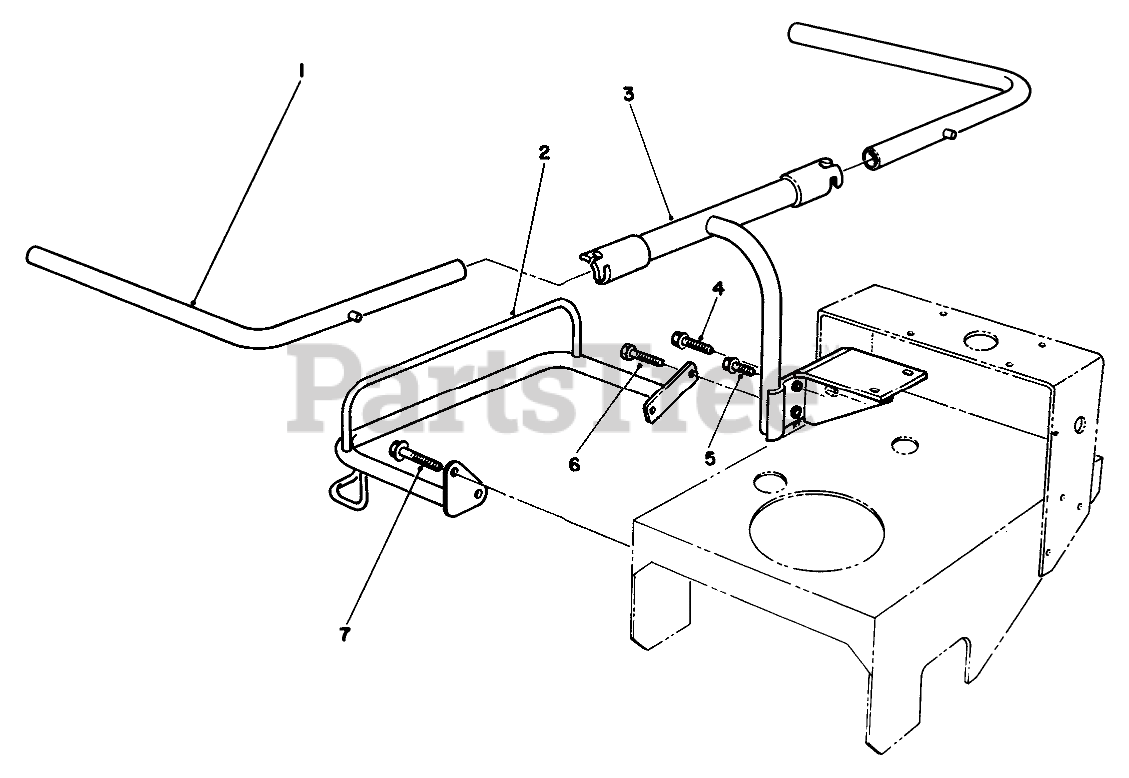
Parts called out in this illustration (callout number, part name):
1	Frame Bagger
2	WHEEL GUARD WA
3	Support-Bagger
4	Screw-Flange Head
5	SCREW-HHF
6	SCREW-HH
7	SCREW-HHF
